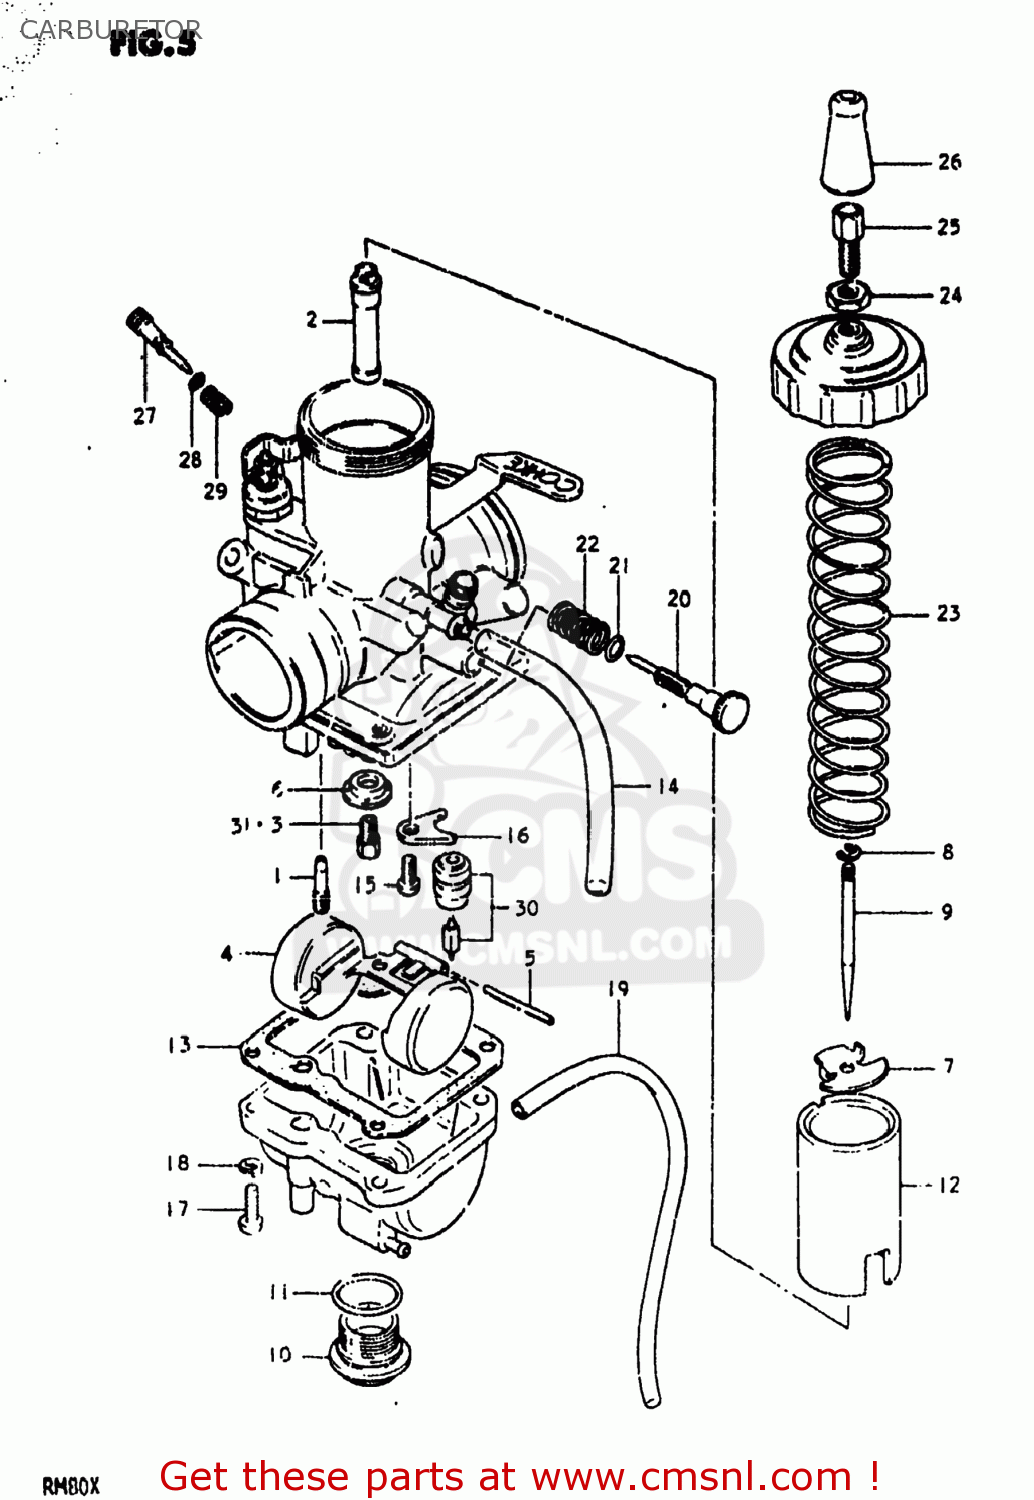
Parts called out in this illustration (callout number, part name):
1	JET,PILOT(35)
2	JET,NEEDLE
3	JET,MAIN(155)
4	FLOAT
5	PIN,FLOAT
6	RING
7	PLATE,THROTTLE VALVE
8	CLIP
9	NEEDLE,JET(5DP39-4)
10	PLUG
11	O RING
12	VALVE,THROTTLE
13	GASKET,FLOAT CHAMBER (NAS)
14	HOSE
15	SCREW
16	PLATE
17	SCREW
18	LOCK WASHER
19	HOSE
20	ADJUSTER
21	O-RING
22	SPRING
23	SPRING,THROTTLE VALVE
24	NUT
25	ADJUSTER,CABLE
26	CAP
27	SCREW,PILOT AIR ADJUSTING
28	O RING
29	SPRING
30	VALVE ASSEMBLY,NEEDLE
31	JET
